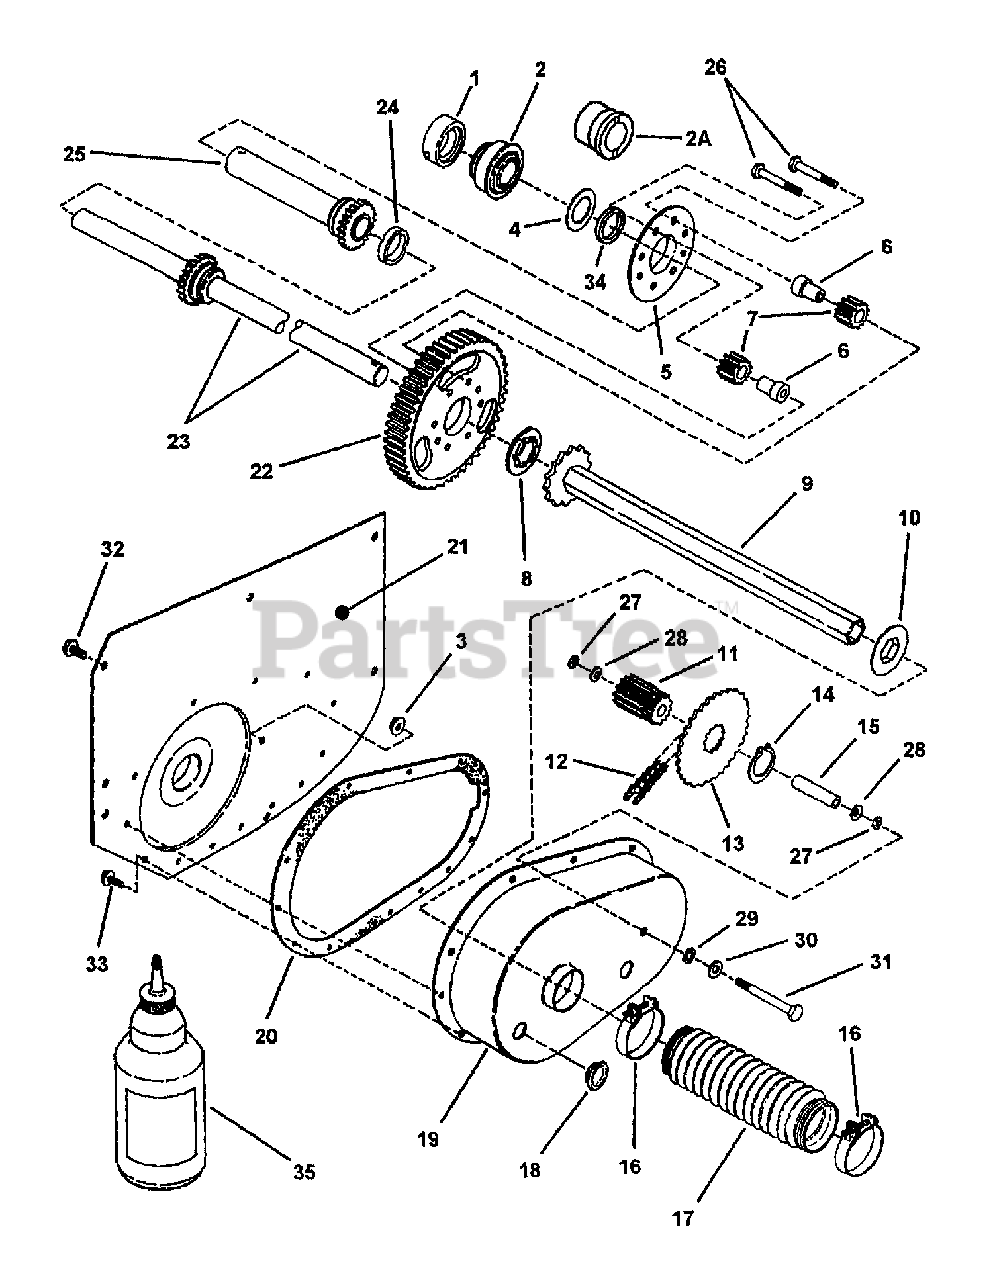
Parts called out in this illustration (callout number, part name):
1	COLLAR, Lock (Includes P/N 90201, 5/16-18 x 5/16" Set Screw)
2	BEARING-BALL, Axle (1.215" ID x 2.5" OD) (R. H. Fender)
2A	BEARING-DX, Axle (1.29" ID x 1.628" OD) (R. H. Fender)
3	NUT, 5/16-24 Flange Lock (Large)
4	WASHER, Thrust
5	PLATE, Differential (8 holes)
6	SPACER, Pinion
7	GEAR, Differential Pinion (12T 12P)
8	WASHER, Thrust
9	* ASSEMBLY, Drive Hex Tube
10	WASHER, Nylon
11	GEAR, 11 Tooth, 10 Pitch
12	CHAIN, 46 Pitch (#35 Endless)
13	SPROCKET, 34T, 3/8P
14	RING, 1-3/16" External Retaining
15	SPACER, Differential Case
16	BOOT CLAMP, 2"
17	BOOT, Axle
18	PLUG, 1/2" Cup Insert
19	CASE, Transmission
20	GASKET, Transmission Case
21	FENDER, Right Hand (1.62" Dia. Hole)
21	FENDER, Right Hand (2.498" Dia. Hole)
22	GEAR, 63 Tooth 10 Pitch (4 Hole)
22	GEAR, 63 Tooth 10 Pitch (8 Hole)
23	ASSEMBLY, Long Axle (Includes Gear)
24	SPACER, Differential Case
25	ASSEMBLY, Short Axle, 23T (Includes Gear)
26	BOLT, 5/16-24 x 1-5/8" Hex Special Lock (Vibresist)
27	5/16" O-RING
28	WASHER, 5/16" Belleville
29	WASHER, 5/16" External Tooth Lock
30	WASHER, .34 x .69 x .08 Flat
31	SCREW, 5/16-24 x 2-5/8" Hex Head Cap
32	SCREW, 5/16-18 x 5/8" Hex Washer Self-Tap
33	SCREW, 1/4-20 x 5/8" Hex Washer Head Self-Tap
34	SPACER, Short Axle (1.30" ID, .145" thick)
35	GREASE, "00" Transmission (24 oz. Required)
